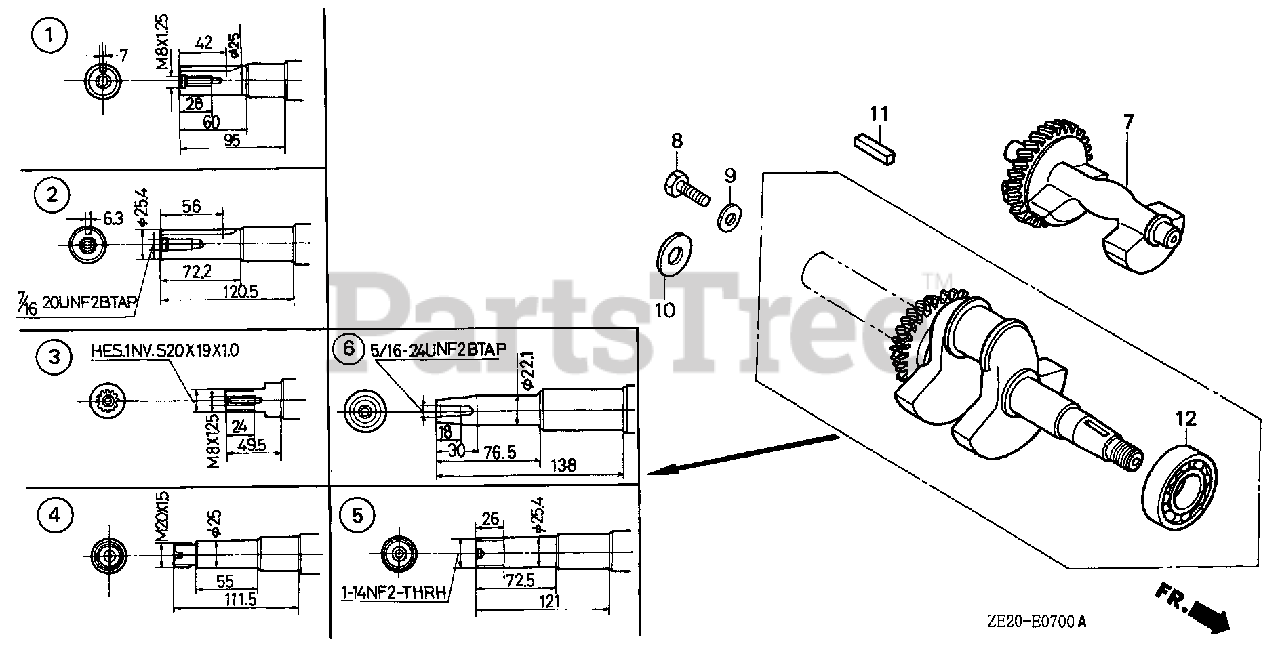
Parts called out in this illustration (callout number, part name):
2	CRANKSHAFT (NOT AVAILABLE)
2	CRANKSHAFT
7	WEIGHT, BALANCER (NOT AVAILABLE)
7	WEIGHT, BALANCER
11	KEY (6.3X6.3X43)
12	BEARING, RADIAL BALL (6206)
